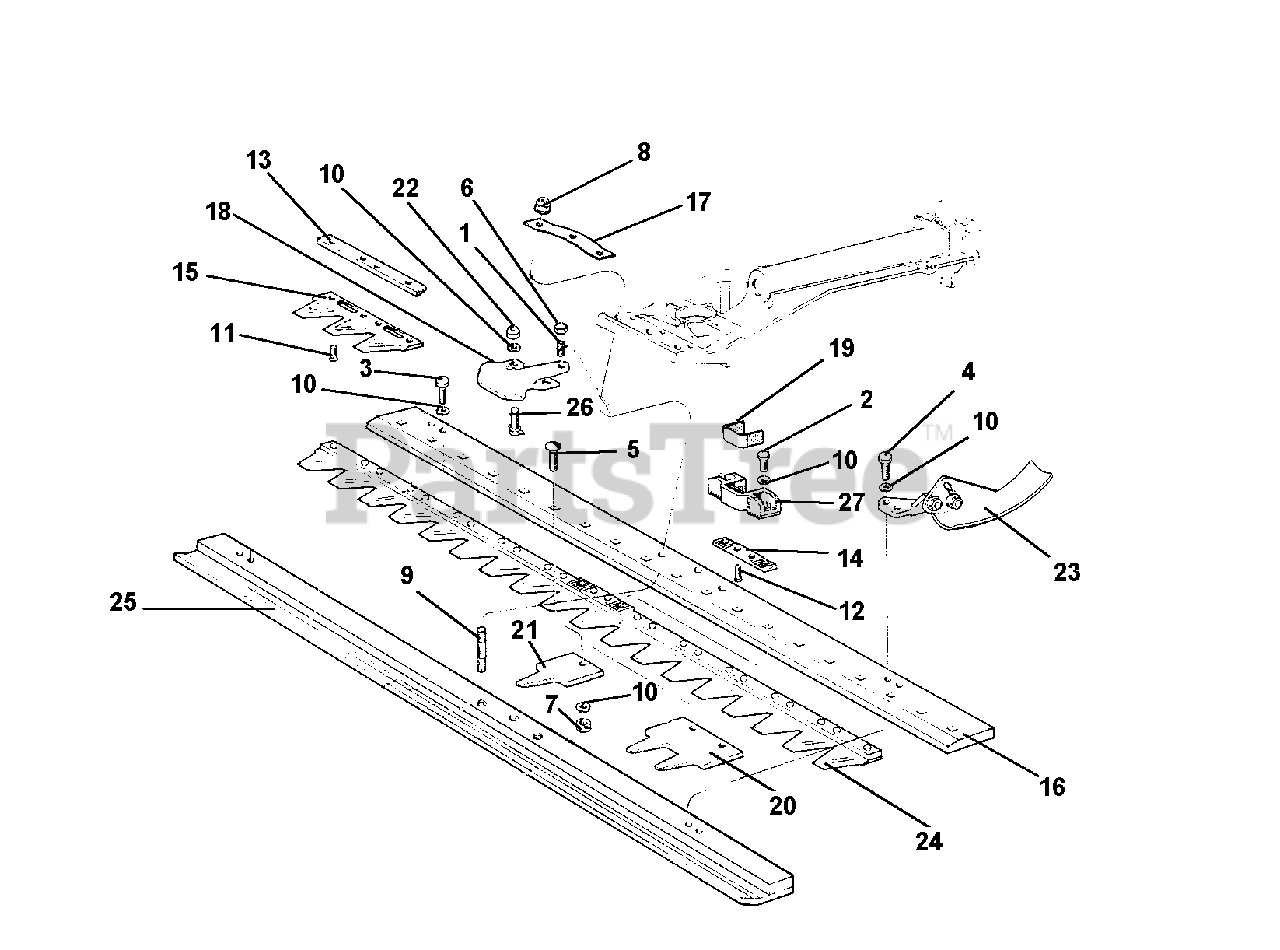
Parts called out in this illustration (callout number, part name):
1	SCREW M8 X 14
2	SCREW M8 X 20
3	SCREW M8 X 25
4	SCREW TE M8 X 30
5	SCREW M8 X 25
10	WASHER, LOCK 8.4
11	RIVET 5.3 X 14
12	RIVET TSV 5.3 X 18
13	BLADE STRIP 40"
14	COUPLER PLATE
15	THREE BLADE SECTION
16	CENTRAL BAR 40"
18	BLADE HOLDER
20	DOUBLE BLADE
21	SINGLE BLADE
22	BEVEL NUT M8
24	BLADE SECTION 40"
26	BLADE HOLDER FASTENER
27	NYLON COUPLER
